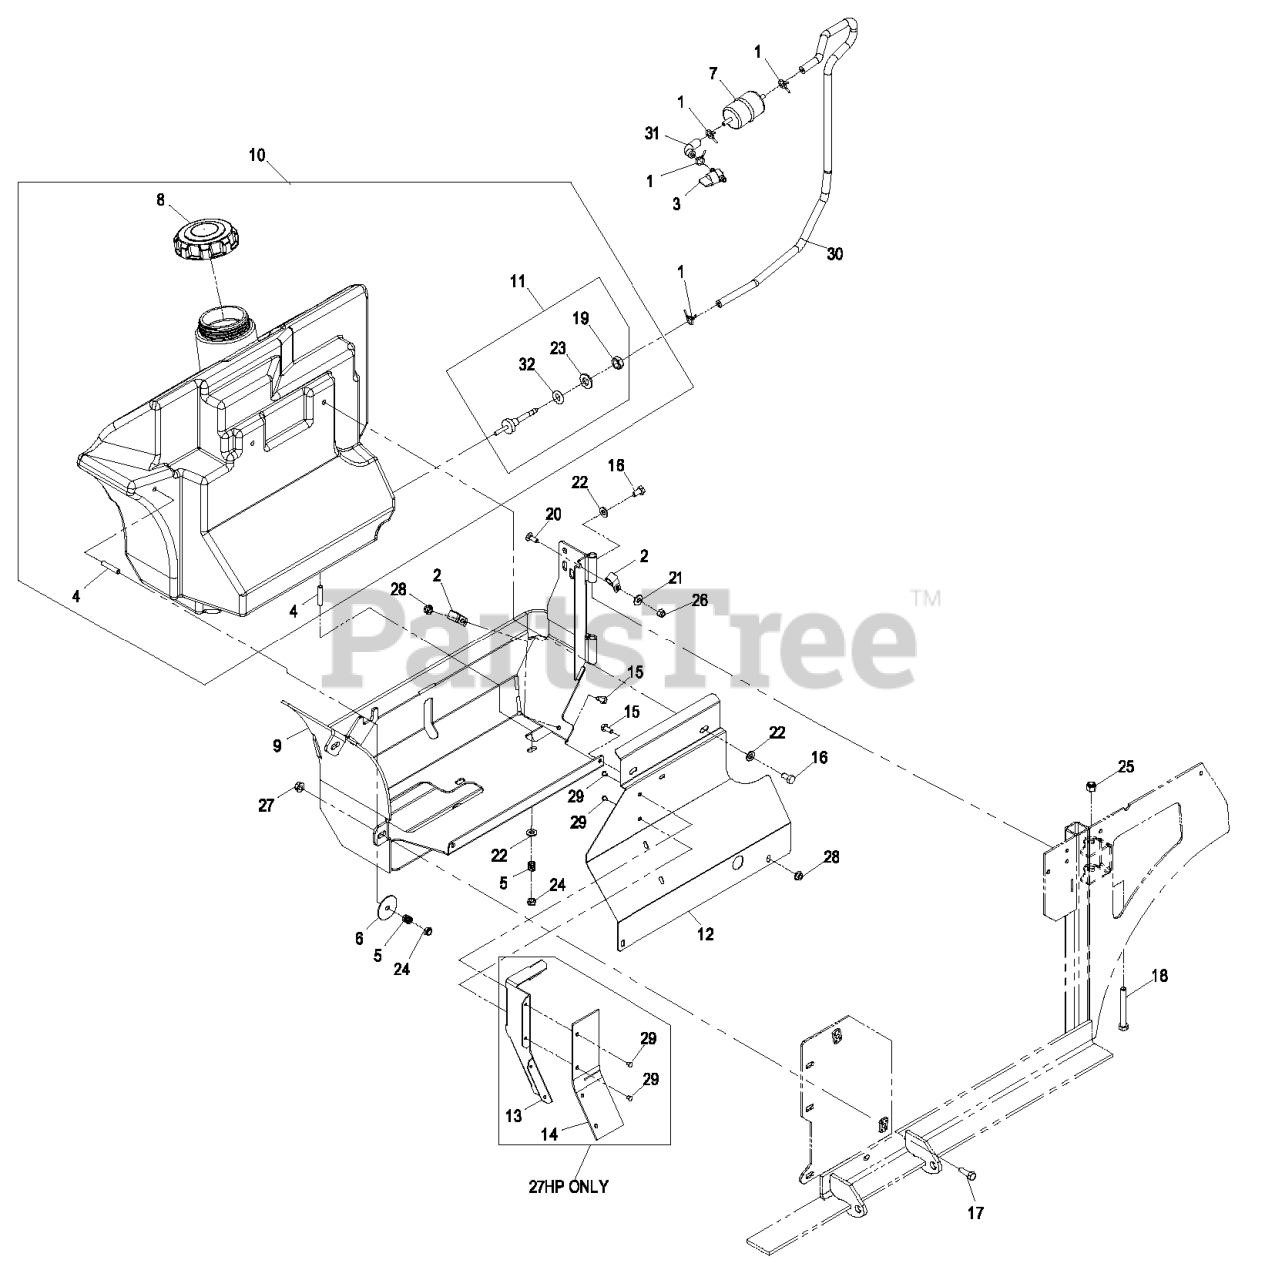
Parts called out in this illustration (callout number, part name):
2	CLIP-LOOM
3	VALVE-FUEL
4	STUD
5	SPRING-TANK, FUEL
7	Part No. 2405010 Fuel Filter
8	CAP-FUEL, GAS
9	Wld, Tank Frame
10	ASM,FUEL TANK W/CAP
11	FITTING-FUEL, BULKHEAD
12	Panel, Tank Shield
13	DEFLECTOR-AIR
14	FLAP-RUBBER
15	SCREW-HH
16	SCREW-HH
17	SCREW-HH
18	SCREW-CARR
19	NUT-JAM
20	BOLT-CARR
21	WASHER-FLAT
22	WASHER-PLAIN
23	WASHER-FLAT
24	NUT-LOCK, NI
25	NUT-LOCK, NI
26	NUT-LOCK, NI
29	RIVET-POP
30	HOSE-FUEL
31	HOSE-FUEL
32	O-RING,BULKHEAD FITTING
